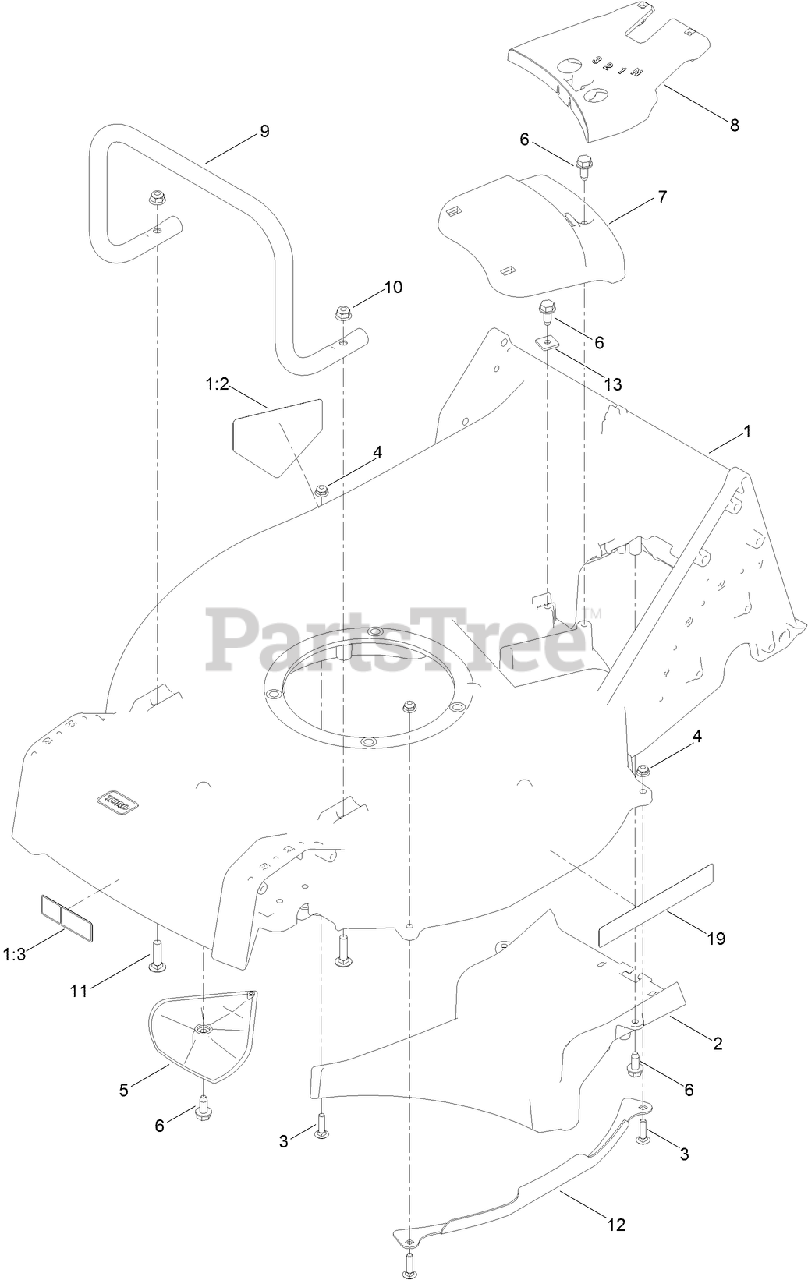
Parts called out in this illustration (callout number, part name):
1	HOUSING ASM
1:2	DECAL-DANGER
1:3	DECAL-WARNING, BLADE
2	FLOOR-CHUTE
3	SCREW-CARR
4	NUT-HF
5	KICKER
6	SCREW-HWHTF
7	COVER-BELT, FRONT
8	COVER-BELT, REAR
9	GUARD-ENGINE
10	NUT-HF, NI
11	SCREW-CARR
12	GUARD-SIDE, DECK
13	CLAMP-CABLE
19	DECAL-RECYCLER
